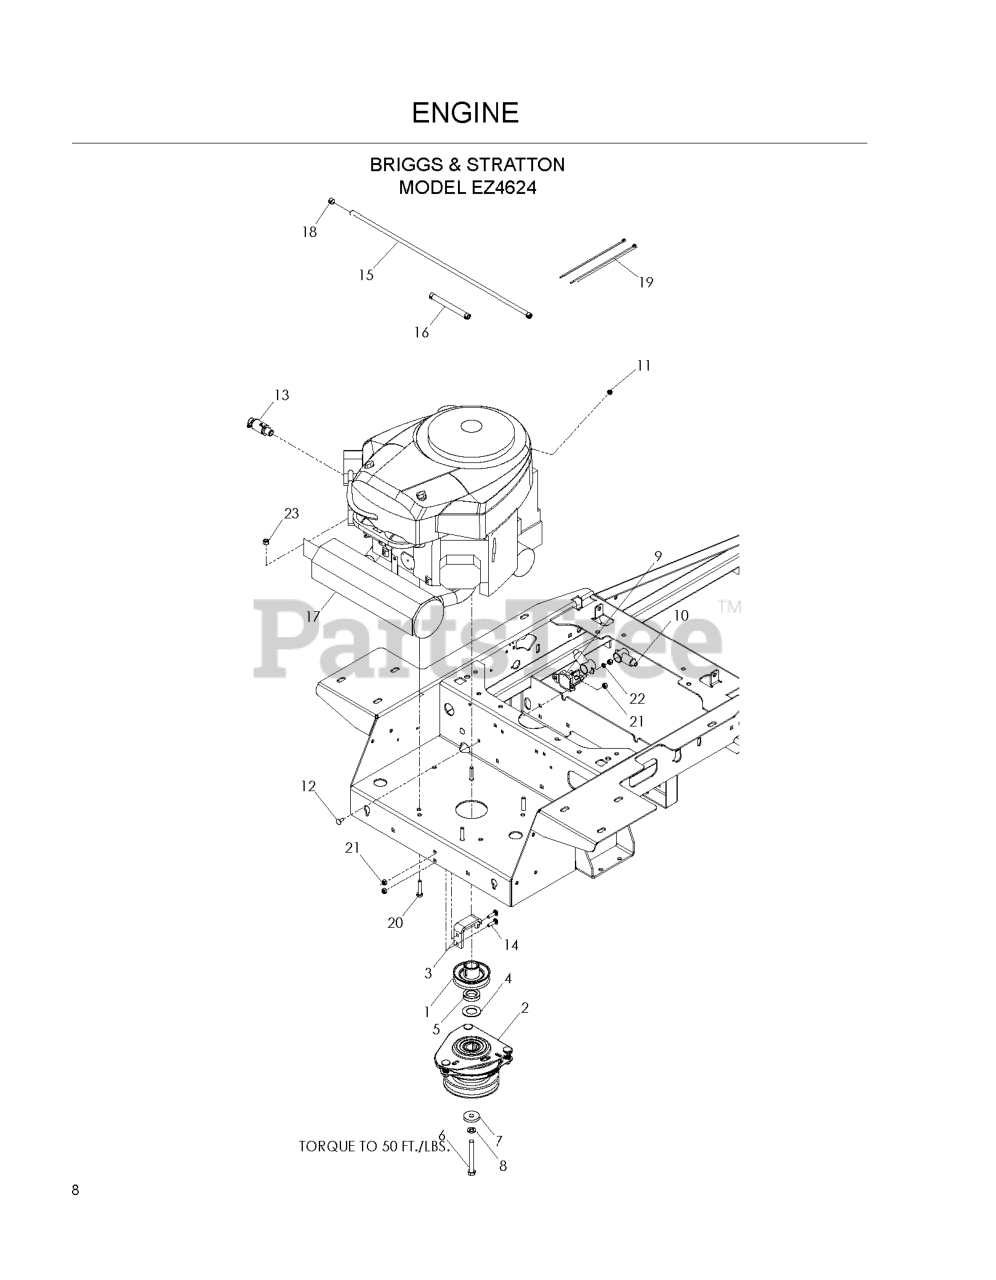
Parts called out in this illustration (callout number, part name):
1	PULLEY, ENGINE
2	CLUTCH, 90 FT/LBS
3	CLUTCH TIE DOWN
6	HCS 7/16-20X3-1/2 GR 5 ZN
7	CLUTCH, WASHER
8	WASHER 7/16 LOCK
11	JAM NUT 1/4C (2 2 PW01)
12	RHSSNB, 1/4-20X5/8
13	OIL DRAIN FITTING
14	RHSNB, 1/4-20 X 1, GR5
15	FUEL LINE 24"
16	FUEL LINE 5"
18	HOSE CLAMP
19	TIE, PLASTIC
20	CAPSCREW 5/16 X 1/1/2 HEX HEAD
21	NUT.1/4-20.HEX.NYLOC.ZD
22	WASHER 1/4 INT TOOTH
23	NUT 5/16 NYLOC
